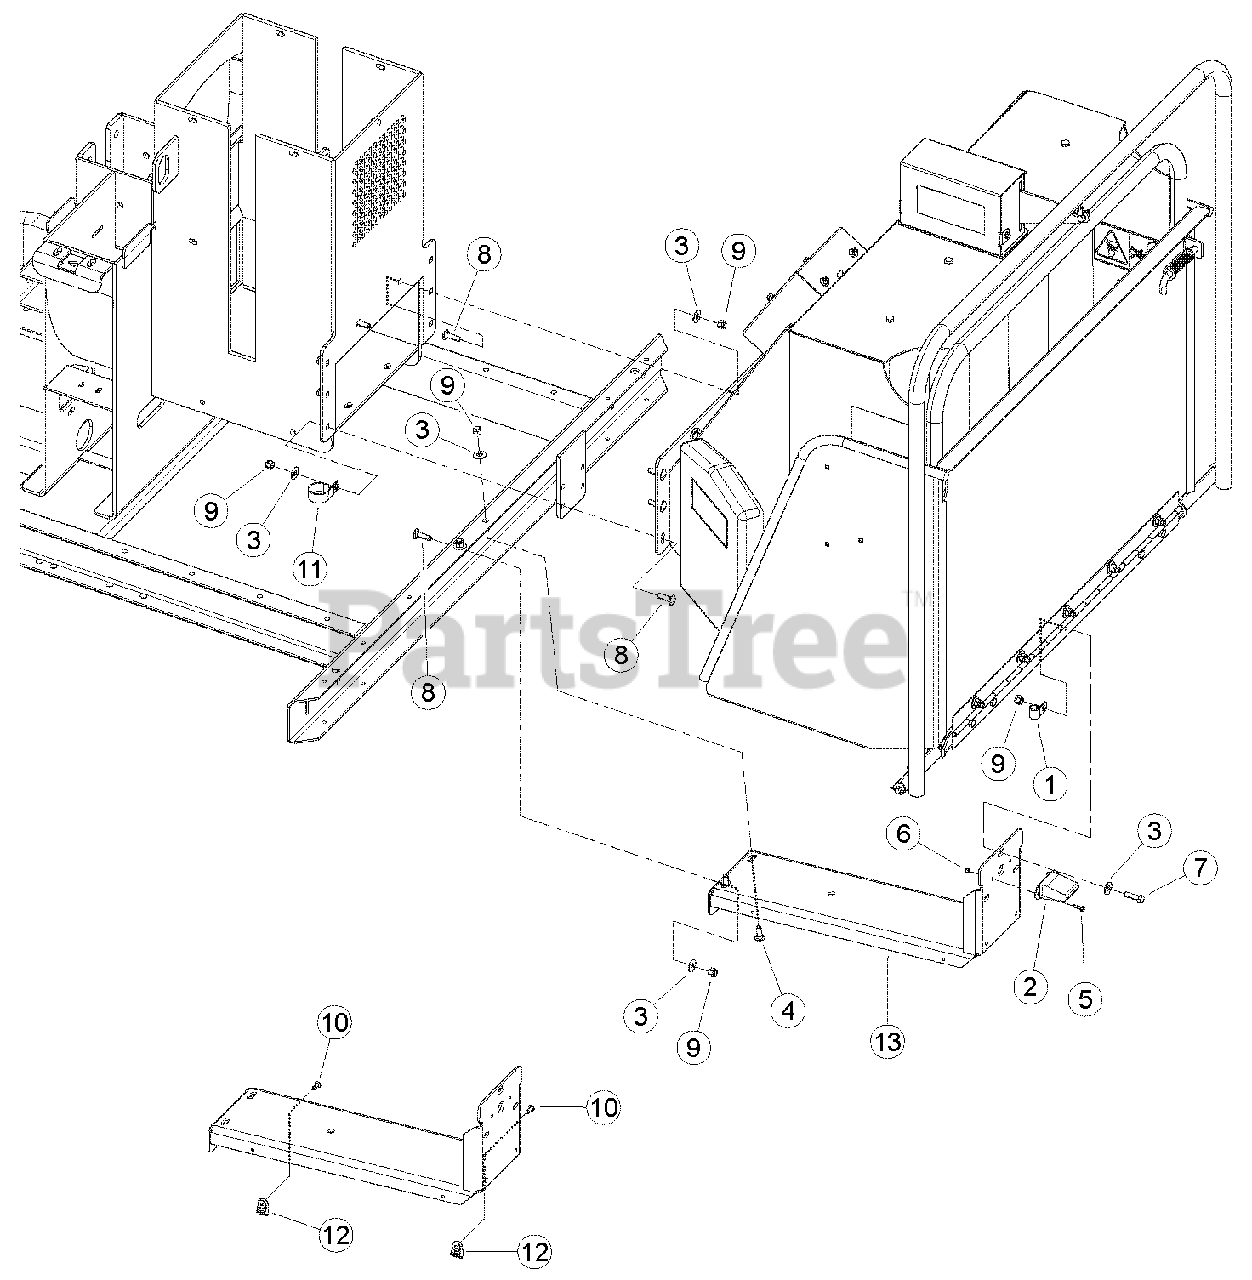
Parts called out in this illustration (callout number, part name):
1	ADAPTER, -10 MORING / -8 MJIC 90 DEG.
2	ADAPTER, -8 MORING / -8 MJIC
3	ADAPTER, -10 MORING / -8 MJIC
4	ADAPTER, -8 MORING / -8 MJIC 90 DEG.
5	MOTOR, 45 CU. IN. HYDRAULIC
6	FILTER, SPIN-ON
7	ADAPTER, -10 MORING / -10 MJIC 90 DEG.
8	ASSEMBLY, SA - 1987 VALVE
9	HOSE ASSEMBLY, -10 FMJIC / -10 FMJIC LD 90 X 21"
10	HOSE ASSEMBLY, -8 FMJIC / -8 FMJIC 90 X 21"
11	HOSE ASSEMBLY, -8 FMJIC / -8 FMJIC 90 X 61"
12	HOSE ASSEMBLY, -8 FMJIC / -8 FMJIC X 61"
13	HOSE, .75 ID. X 24" 100R4 HYD.
14	CLAMP, 1" OD. HOSE T-BOLT
15	PUMP, PB CW HI/LO .646 DISP.
16	ADAPTER, -10 MORING / .75 90 BEAD HOSE
17	ADAPTER, -8 MORING / -8 MJIC 90 DEG.
18	WELDMENT, HYDRAULIC TANK
